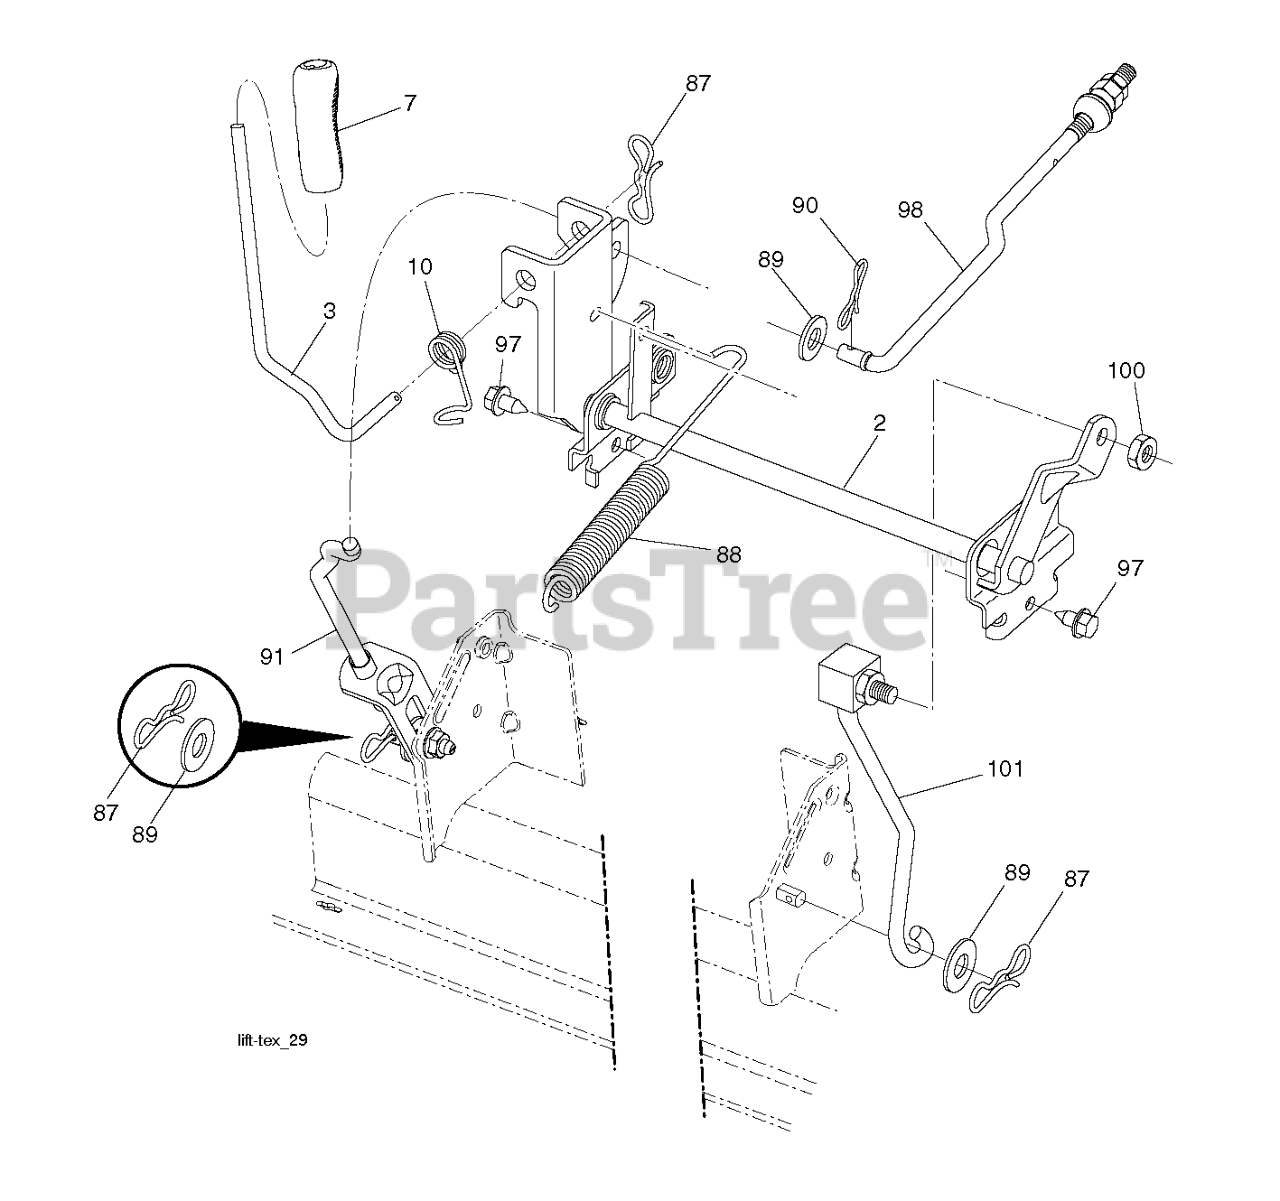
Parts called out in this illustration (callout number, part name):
2	SHAFT.ASM.CROSS.LIFT
3	LEVER.LIFT.HANDLE.LT
7	GRIP.HANDLE.LIFT.PVC.BLACK
10	SPRING.TORSION.LIFT.HANDLE
87	PIN.COTTER.7/16.BOW TI.
88	SPRING.LIFT.ASSIST
89	WASHER.CLEAR.ZINC
90	PIN.COTTER.5/16.BOW TI
91	LINK.ASM.LIFT.REAR
97	SCREW, 3/8-16X3/4
98	LINK.ASM.SUSP.FRONT.MW
100	LOCKNUT
101	LINK.ASM.LIFT.FIXE.38/42/46"
